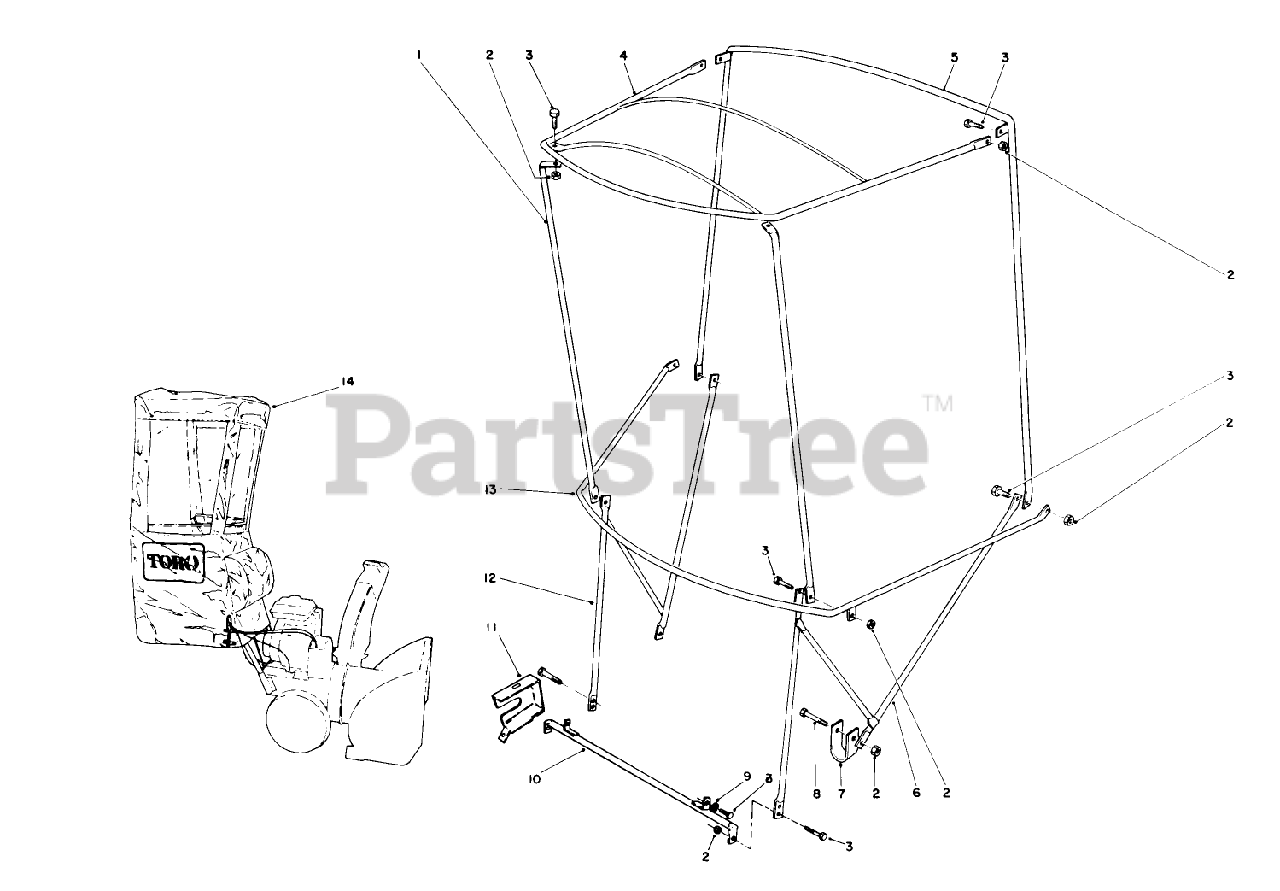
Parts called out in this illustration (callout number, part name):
2	NUT-HEX, SIDE DEFORM
3	SCREW-HH
4	Top Frame
5	BOW-VERTICAL, REAR
6	Bracket-LH
7	CLAMP
8	SCREW-HH
9	WASHER-FLAT
10	Bracket-Base
11	COVER-LOCK, LEVER
12	BRACKET-RH
13	BOW-CURVED
14	Vinyl Cover
